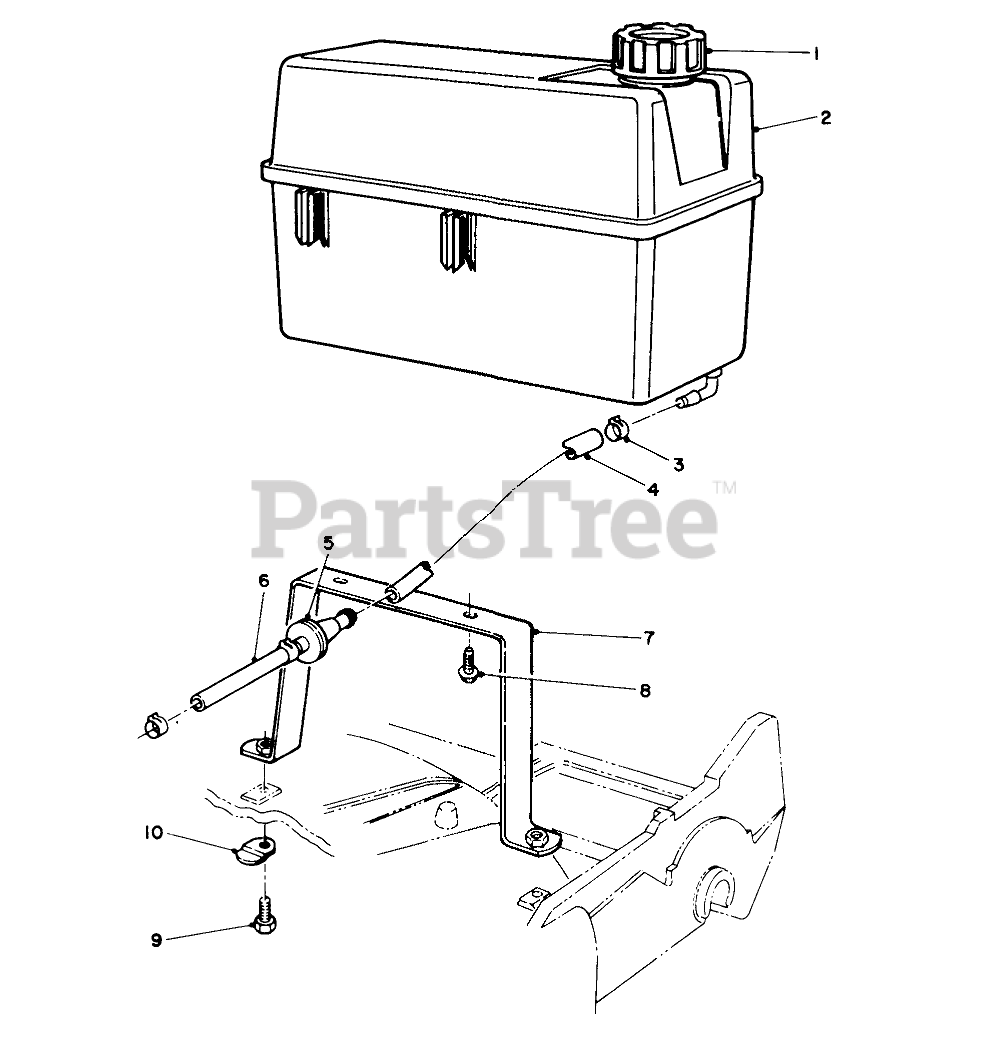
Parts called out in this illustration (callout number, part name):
1	GAS CAP ASM
2	Tank-Gas
3	CLAMP-FUEL LINE
4	HOSE-FUEL
5	FILTER-FUEL
6	HOSE-FUEL
7	Wa-Base
8	SCREW-HWH
9	SCREW-HH
10	SHIELD-RETAINER
